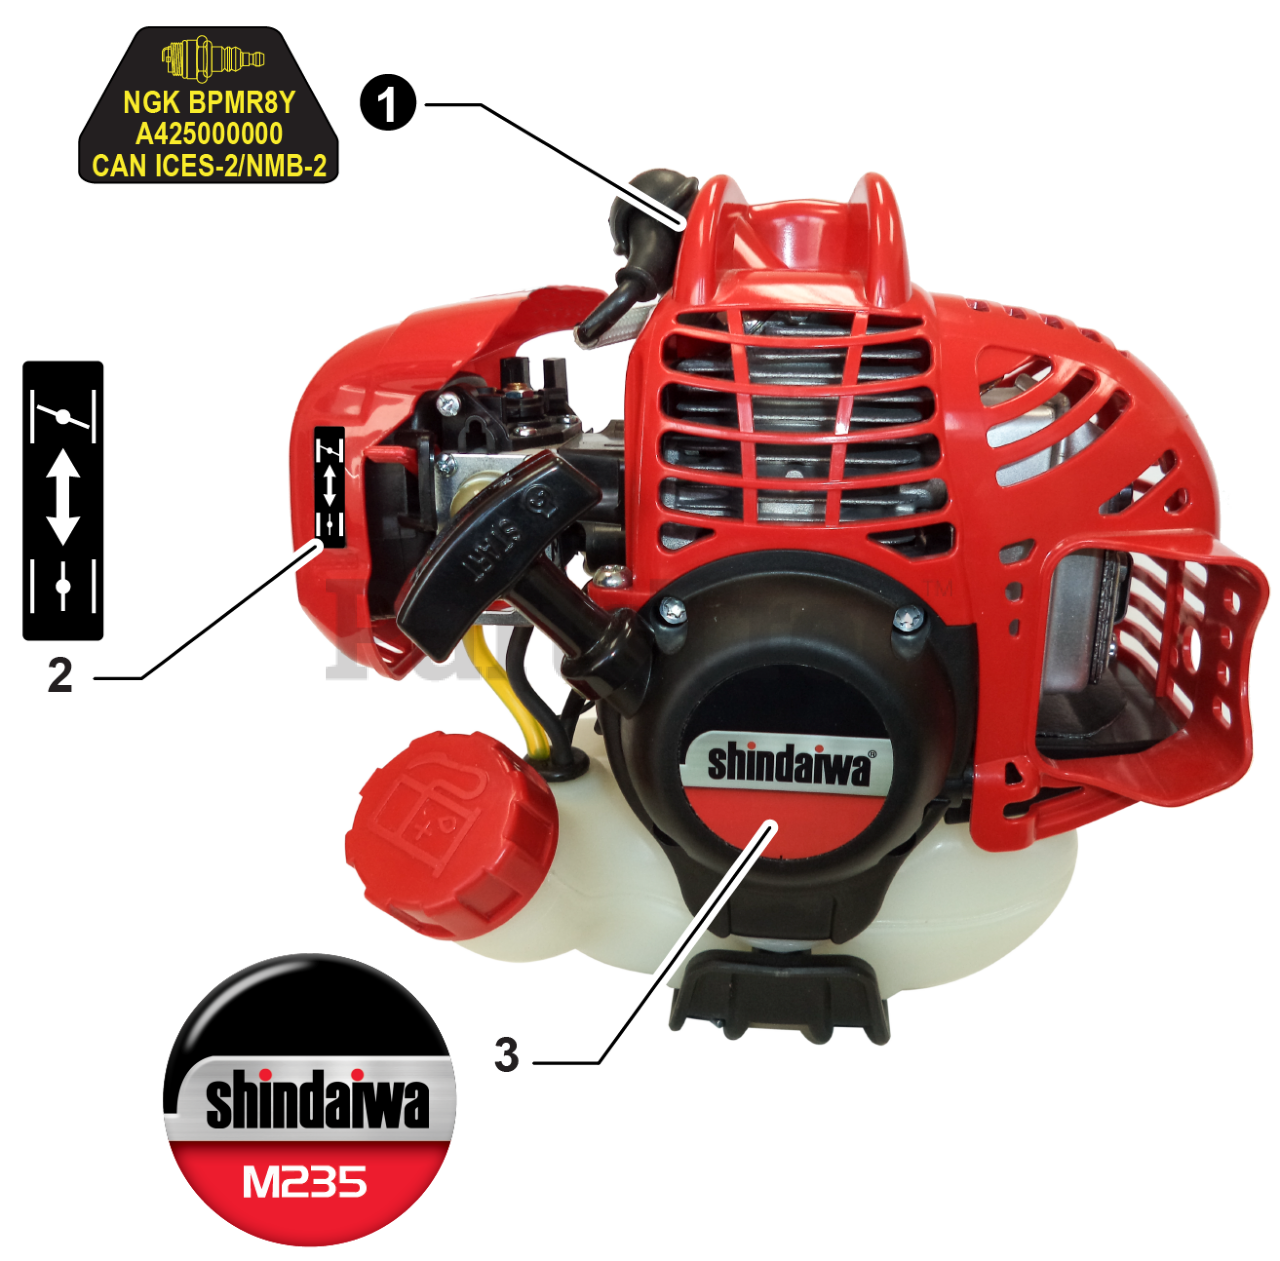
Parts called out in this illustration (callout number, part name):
1	LABEL - SPARK PLUG - BPMR8Y
2	LABEL - CHOKE
3	LABEL - SHINDAIWA - M235
